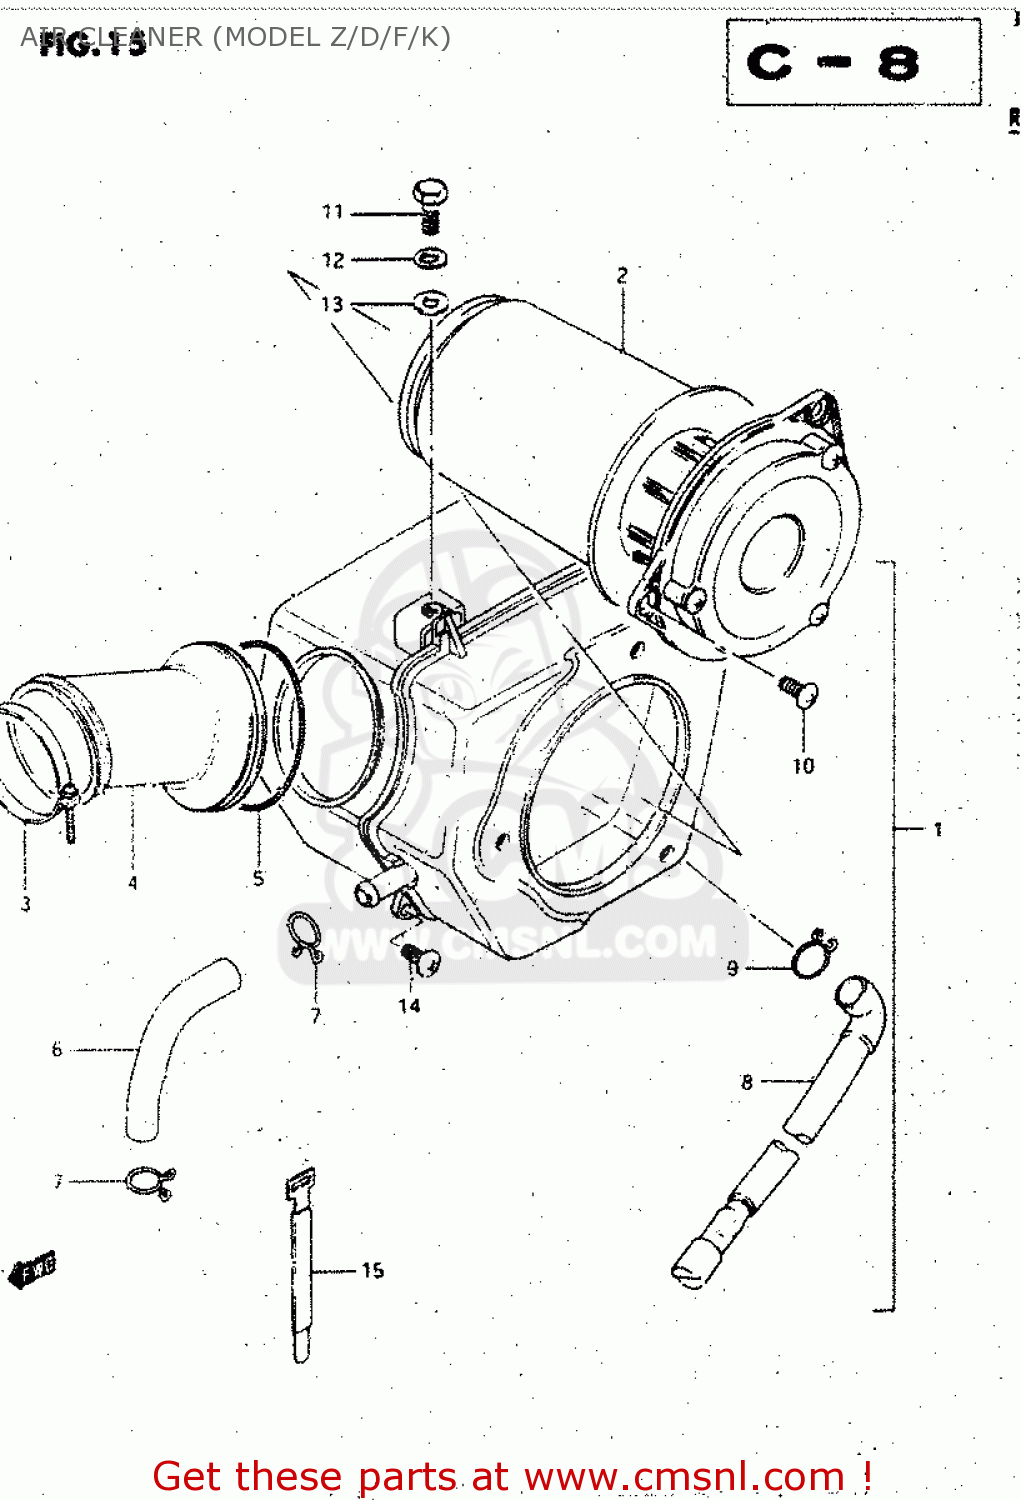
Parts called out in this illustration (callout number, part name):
1	CLEANER ASSY
2	FILTER
3	CLAMP
4	TUBE, OUTLET
5	CLAMP,AIR CLEANER SIDE
6	TUBE,BREATHER
7	CLIP,BREATHER TUBE
8	DRAIN TUBE
9	CLIP
10	SCREW
11	BOLT
12	WASHER,LOCK
13	WASHER
14	SCREW
15	CLAMP L:110
